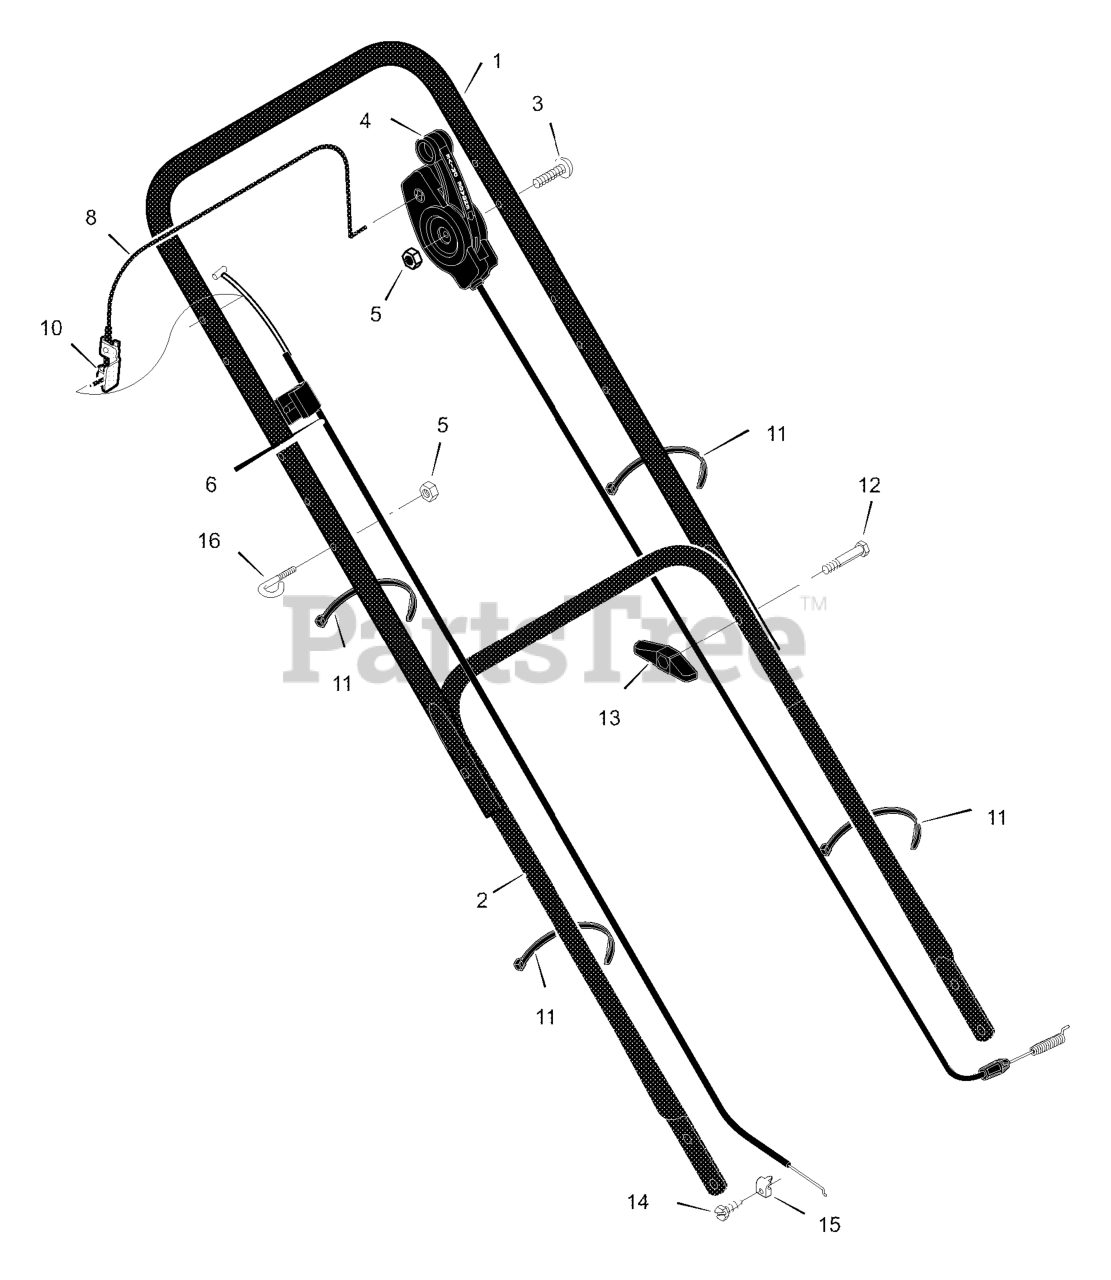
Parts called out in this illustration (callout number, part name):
1	Handle, Upper (Gray)
2	Handle, Lower (Gray)
4	Control, Drive
5	Locknut
6	Cable, Stop
8	Lever, Stop
10	Bracket, Stop Lever
11	Fastener, Cable
13	Knob
16	Guide, Rope
